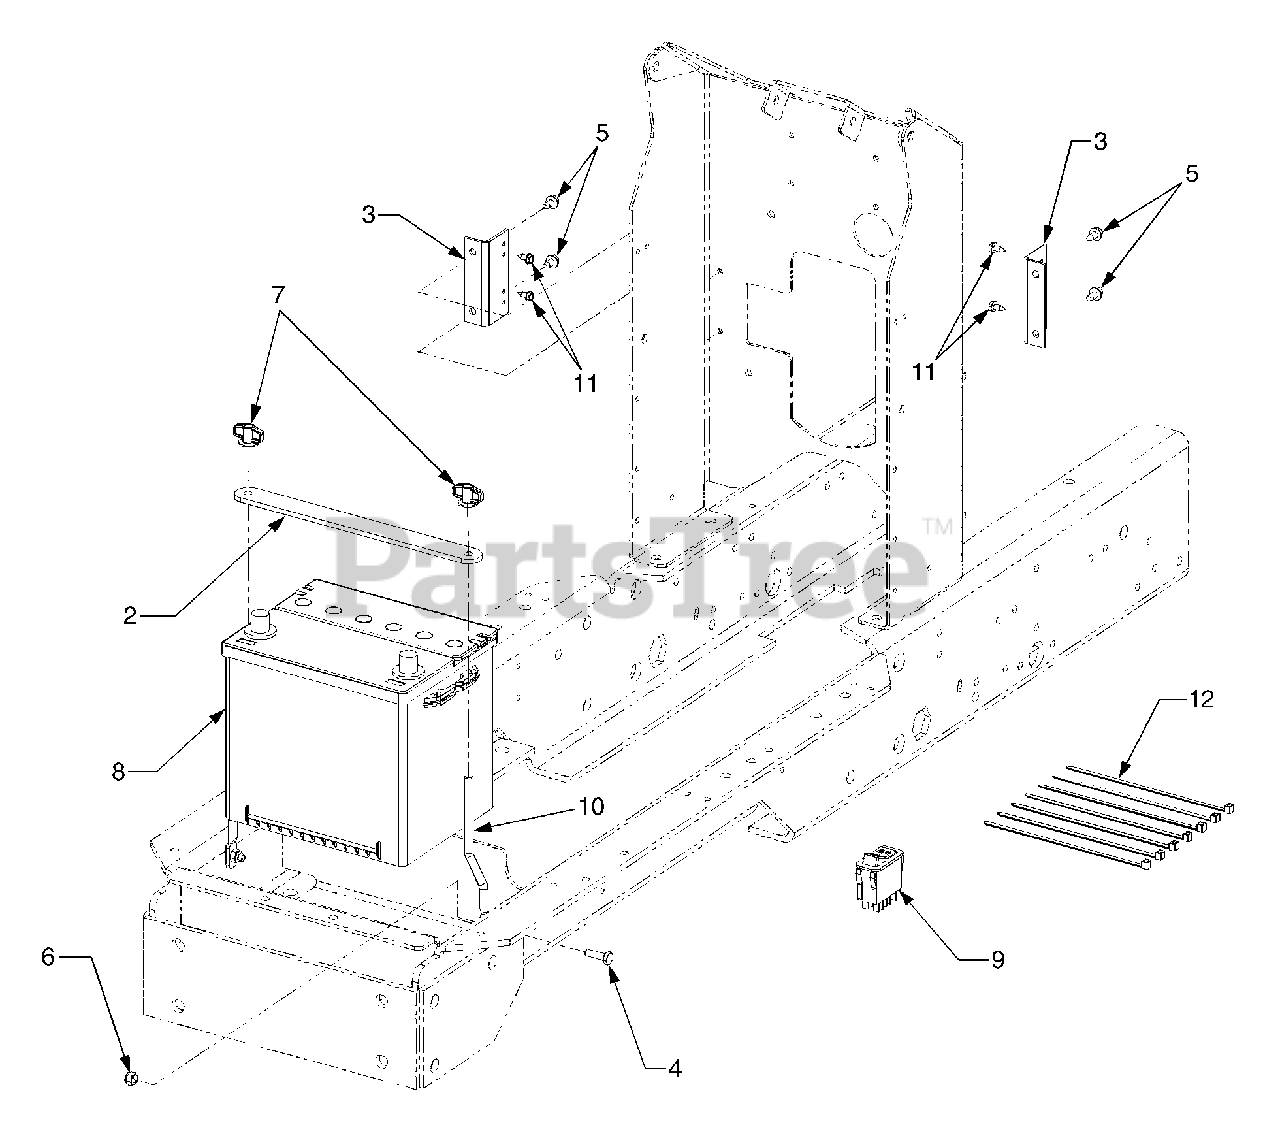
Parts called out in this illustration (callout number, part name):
2	Strap, Battery Holddown
5	Screw, Hex Wash Hd. Tapp 1/4-20 x 5
6	Nut, Hex Nylon Insert Lock, 1/4-20
7	Nut, Wing w/Bell Washer, 5/16-18
8	Battery, 500 cca Dry
9	Switch, PTO Reverse
10	Rod, Battery Hold down
11	Screw, Hex Tapp, #10-16 x .5
12	Tie , Cable
